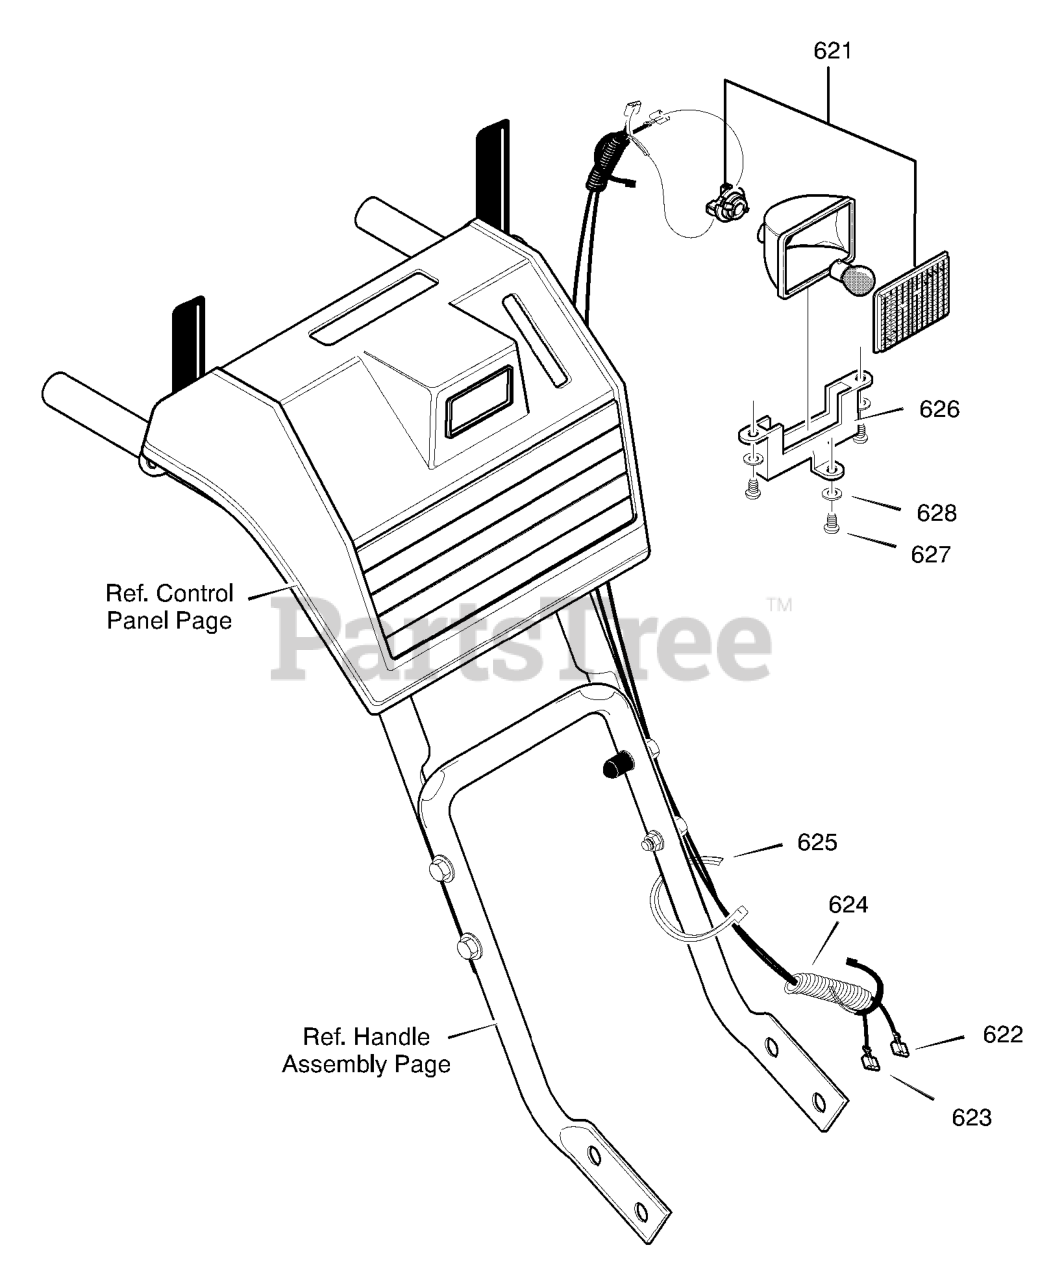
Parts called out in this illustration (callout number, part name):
621	HEADLIGHT ASSY
622	WIRE, ALTERNATOR
623	WIRE, HEADLIGHT
624	CONDUIT, SPLIT
625	CABLE TIE
626	BRACKET, HEADLAMP
628	WASHER, FLAT
